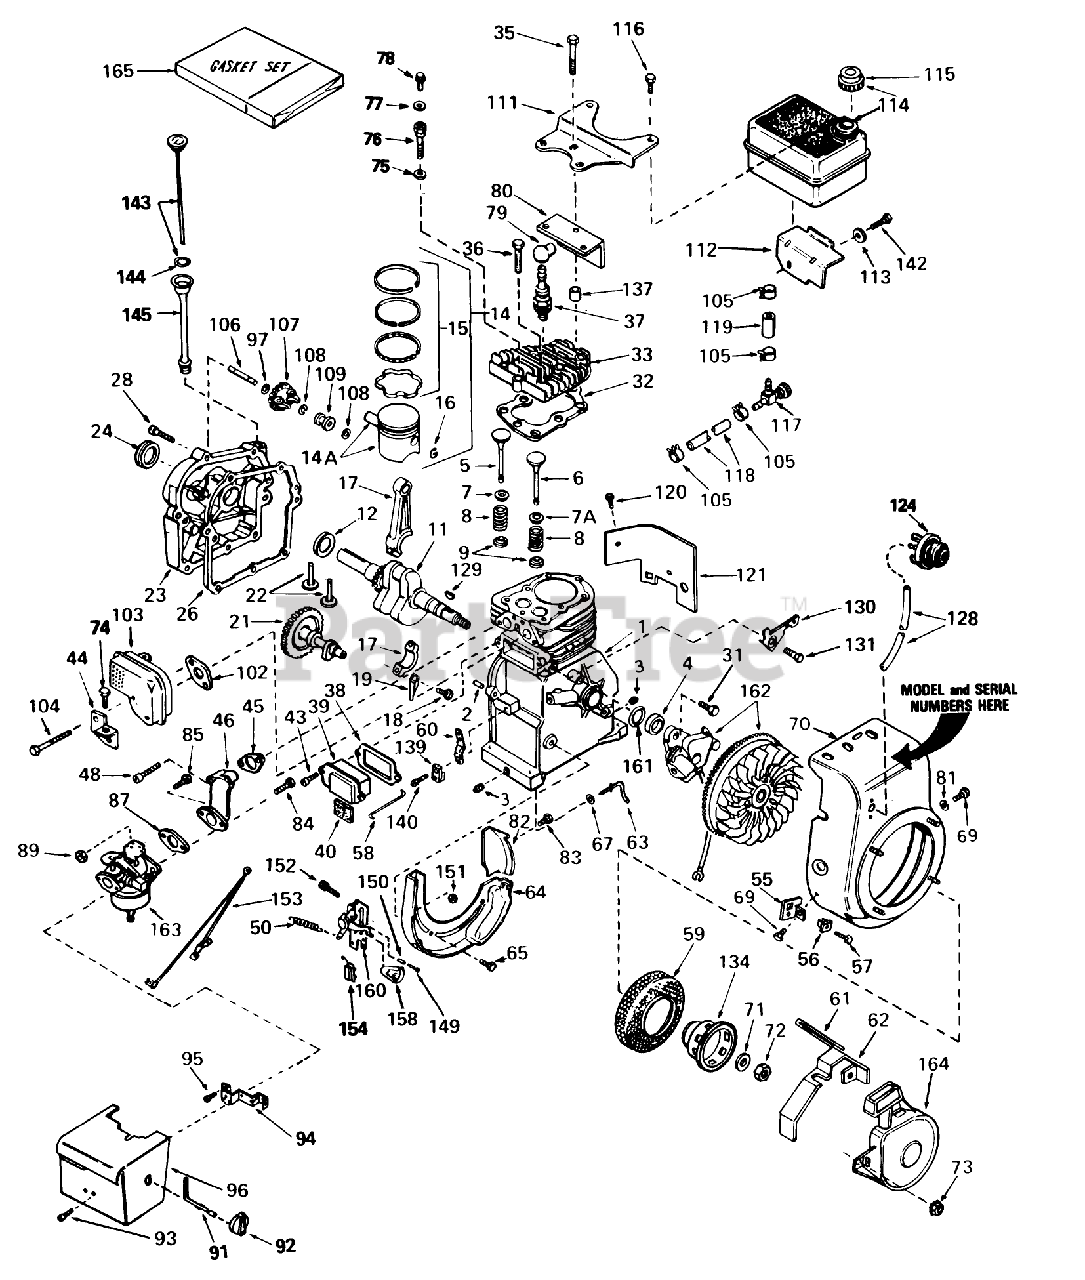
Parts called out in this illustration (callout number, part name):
1	Cylinder Assy. (Incl. Nos.2, 34)
2	Pin-Dowel
3	Plug-Drain, Oil (SQH 1/4-18)
4	Seal-Oil
5	Valve-Intake Standard (Incl. Ref. #151)
5	Valve-Intake 1/32" oversize (Incl. Ref. #151)
6	Valve, Exhaust (Std.)(Incl. No. 40)
6	Valve, Intake (1/32" oversize)(Incl. No. 40)
7	Cap-Upper Valve Spring
7A	Cap, Upper Valve Spg (Exhaust)
8	Spring-Valve
9	Cap-Valve, Spring
11	Crankshaft ASM
12	Washer-Thrust
14	Piston, Pin Ring Assy., (Incl. Ref. #15 16) (Std.)
14	Piston, Pin Ring Assy., (Incl. Ref. #15 16) (.010 Oversize)
14	Piston, Pin Ring Assy., (Incl. Ref. #15 16) (.020 Oversize)
14A	Piston Pin Assy. (Incl. Ref. #16) (Std.)
14A	Piston Pin Assy., (Incl. Ref. #16) (.010 Oversize)
14A	Piston Pin Assy. (Incl. Ref. #16) (.020 Oversize)
15	Ring Set-Piston Std.
15	Ring Set-Piston .010 oversize
15	Ring Set-Piston .020 oversize
16	Ring-Retaining, Piston Pin
17	Rod Assy., Connecting (Incl. Nos. 18 19)
18	Bolt-Rod, Connecting
19	Dipper-Oil
21	Camshaft
22	Lifter-Valve
23	Cover, Cylinder (Incl. Ref. #24 106)
24	Seal-Oil
26	Gasket-Cylinder Cover
28	Screw (1/4-20 x 1-1/4)
31	Screw
32	Oil Fill Tube
33	Head Cylinder
35	Screw (5/16-18 X 2)
36	Screw (5/16-18x1-1/2)
37	Plug, Spark (J17LM or equiv.)
37	Plug, Spark (Champion RCJ-8)
38	Gasket Breather
39	Breather Assembly (Incl. Nos. 52 84)
40	Element-Breather
43	Screw
44	Bracket-Cover, Carburetor
45	Gasket-Intake
46	Pipe-Intake
48	Screw (1/4-20 x 1-19/32)
50	Spring-Extension
55	Bracket
56	Grommet
57	Screw
58	Link-Governor to Throttle
59	Screen-Starter
60	Lever-Governor
61	Seal, Snowguard
62	Guard-Starter
63	Rod-Governor
64	Baffle-Blower Housing
65	Screw (1/4-20x19/32)
67	Washer-Flat
69	Screw
70	Housing-Blower
71	Washer-Belleville
72	Nut-Flywheel
73	Nut and Lock Washer (1/4-28)
74	Screw (10-24 x 3/8)
75	Washer-Flat
76	Screw ( 5/16-18 x 1-1/2)
77	Washer
78	Screw
79	Cover-Spark Plug
80	Baffle-Heat
81	Washer
82	Baffle-Extension
83	Screw-Hex Washer Hd.
85	Screw-Fil. Hd.
87	Gasket
89	Nut and Lock Washer (1/4-28)
91	Rod-Choke
92	Knob-Control
93	Screw (8-32 X 5/16)
94	Bracket-Choke
95	Screw (10-32 x 1/2)
96	Cover, Carburetor
97	Washer-Flat
102	Gasket-Exhaust
103	Muffler
104	Screw-Fil. Hd.
105	Clamp-Line, Fuel
106	Shaft-Governor
107	Governor Gear ASM
108	Ring-Retaining
109	Spool-Governor
111	Plate-Fuel Tank
112	Bracket-Fuel Tank
113	Washer
114	481-1261 SENATOR TI
115	Cap, Fuel
116	Screw (1/4-15x7/8)
117	Valve-Shut Off
118	Line-Fuel
119	Line-Fuel (8.62)
120	Screw
121	Extension-Blower
124	Primer Assy.
128	Line, Primer
129	Key-Flywheel
130	Bracket-Hold Down
131	Screw (10-24 x 9/16)
134	Cup-Starter
137	pacer
139	Clamp-Lever, Governor
140	Screw
142	Screw Assembly
143	Dipstick
144	O-Ring
145	Tube Fill
149	Screw
150	Spring-Compression
151	Nut-Lock
152	Screw
153	Wire-Ground
154	Terminal
158	Knob-Control
160	Control Assembly, Speed (Incl. Ref. #155 thru 158 160)
161	Gasket Stator
162	Magneto (The complete magneto in not available as an assembly. The magneto number is shown for reference purposes only. Order component parts individually, as shown in parts list)
163	Carburetor (Incl. Ref. #87)
164	Starter Assy., Rewind
165	Gasket Set
